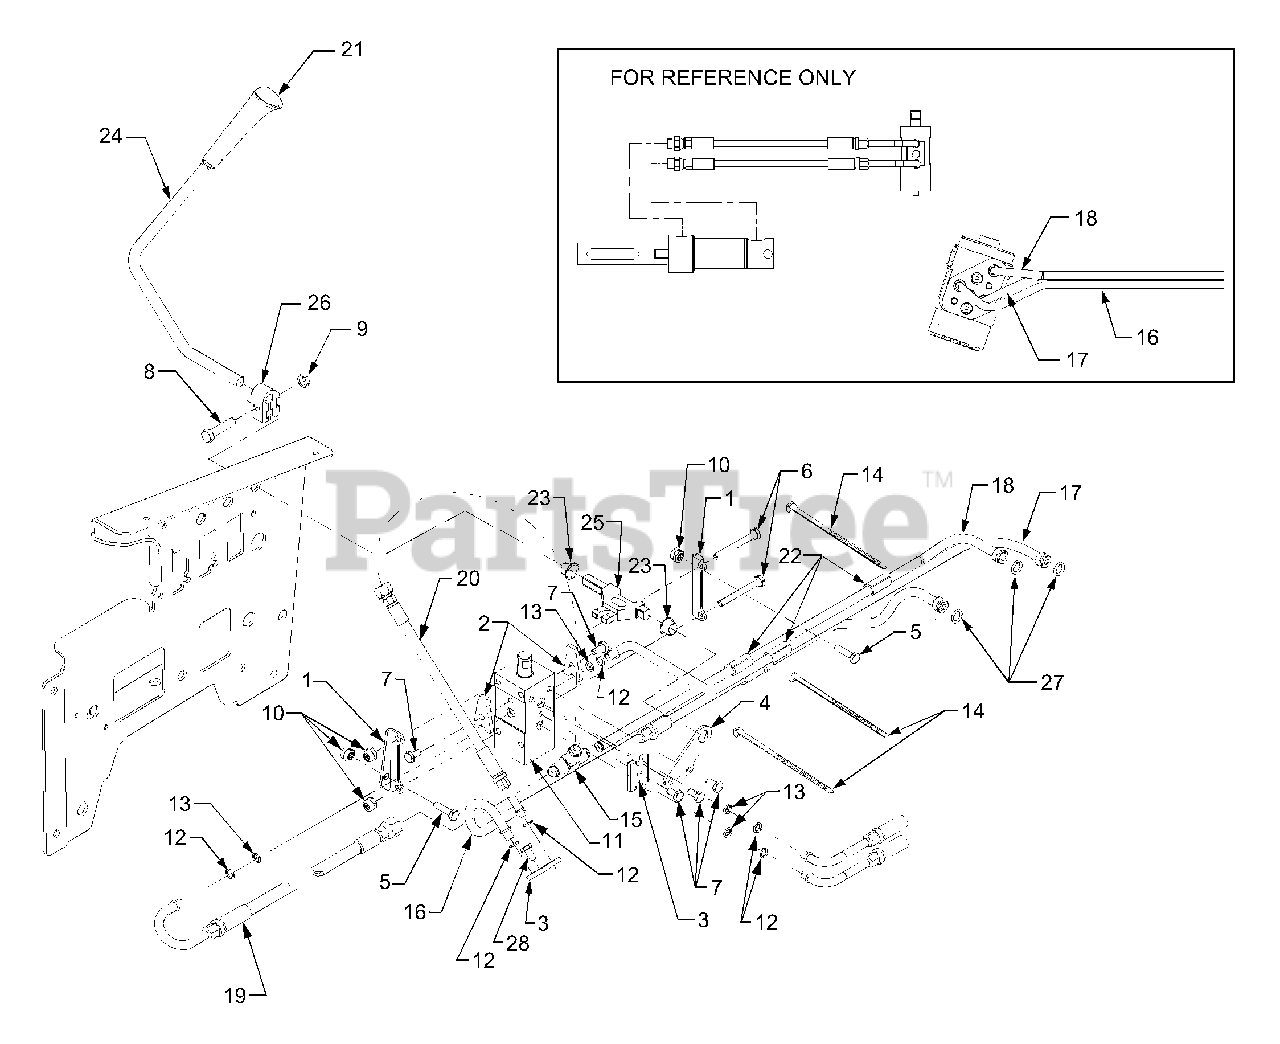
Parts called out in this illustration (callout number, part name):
1	Bracket, Valve Mounting
2	Clamp, Side Valve
3	Clamp, Double Valve
5	Screw, Hex Cap 1/4-20 x 1.0 GR5
6	Screw, Hex Cap 1/4-20 x 2.25 GR5
7	Screw, Hex Cap 1/4-20 x .50 GR5
8	Screw, Hex Cap 5/16-18 x 1.375 GR5
9	Nut, Hex Insert Lock, 5/16-18
10	Nut, Hex Flange Lock, 1/4-20
11	Valve, Hydraulic
12	O-Ring, Backup
13	O-Ring
14	Cable Tie
15	T-Fitting, 9/16-18 Thrd.
16	Tube, Hydraulic (Pump to Strng)
17	Tube, Hydraulic (Aux. from Strng)
18	Tube, Hydraulic (Strng Return)
19	Tube, Hydraulic (Aux Return)
20	Tube, Hydraulic (Return to Pump)
21	Knob, Lift
22	Rubber Spacer
23	Bearing, Nylon Flange
24	Handle, Center Lift Valve
25	Link, Lift
26	Clamp, Handle
27	O-Ring, .426 x .566 x .070
28	Screw, Hex Cap 1/4-20 x .62 GR5
